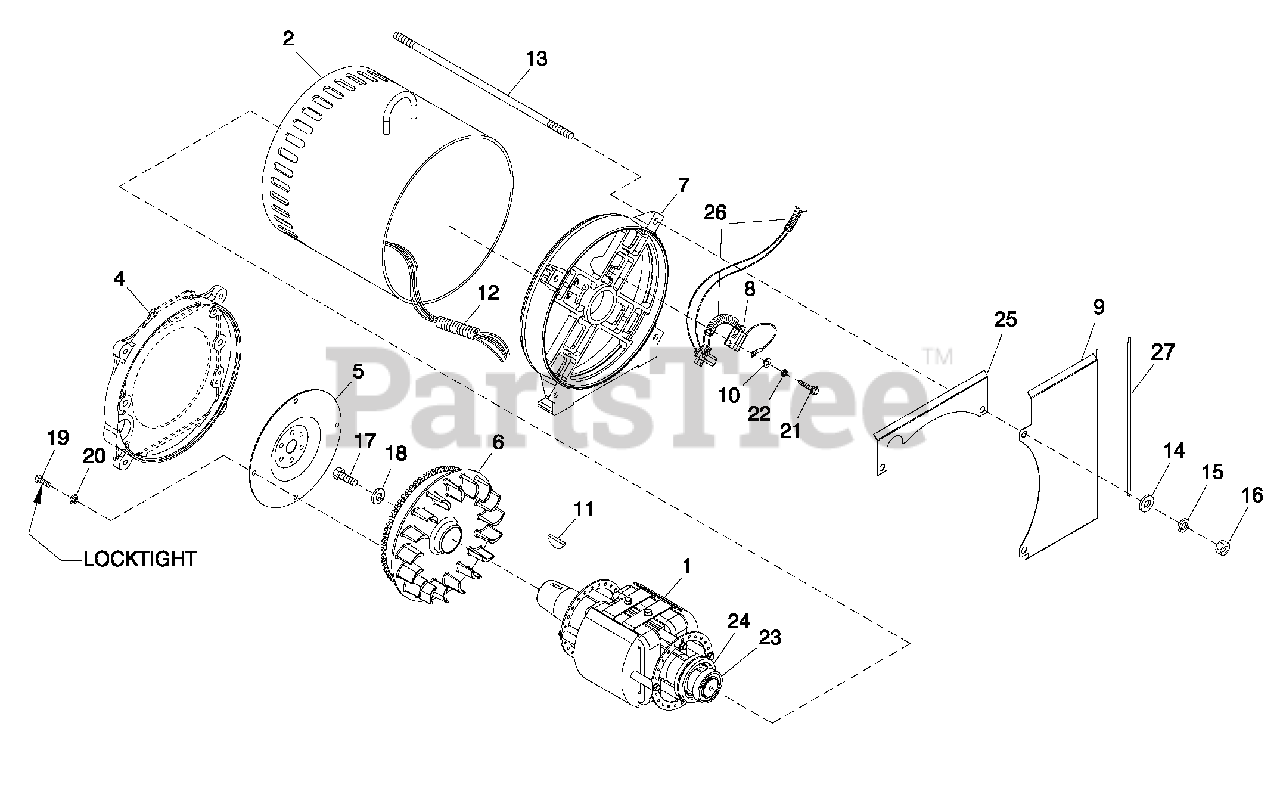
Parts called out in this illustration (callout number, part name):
1	ROTOR-2390-45KD1 CPL
2	RTR 390 35KD1 CPL
3	INSTR HYP0T TEST (N0T SH0WN)
4	ENGINE ADAPTER
5	FLEXPLATE
6	ASSY FLYWHEEL CPL W/40MM FAN B
7	REAR BEARING CARRIER 390/DRCT
8	ASSY BRUSH H0LDER 390/HSB
9	GUARD REAR BEARING CARRIER
10	WASHER FLAT #8 ZINC
11	KEY W 00DRUFF #E
12	C0NDUIT FLEX 1.0" ID (35" LG)
13	STUD M 14-2.0 570 G5 ZINC
14	WASHER FLAT M14
15	WASHER L0CKM14
16	NUT HEXM14-2.0G8YEL CHR
17	SCREW HHCM16-2.0X 45 G8.8
18	SPACER .69 X 2.75 X .37 ST/ZNC
19	SCREW HHC M10-1.50 X 16 G10.9
20	WASHER L0CKM10
21	SCREW HHTT M4-0.7 X 16 BP
22	WASHER L0CK#8-M4
23	BALL BEARING-45 MM
24	SLIP RING MACHINED
25	GUARD REAR BEARING CARRIER
26	C0NDUIT FLEX .38" ID (60")
27	TRIM VINYL BLACK 1/8GP (16.5"LG)
